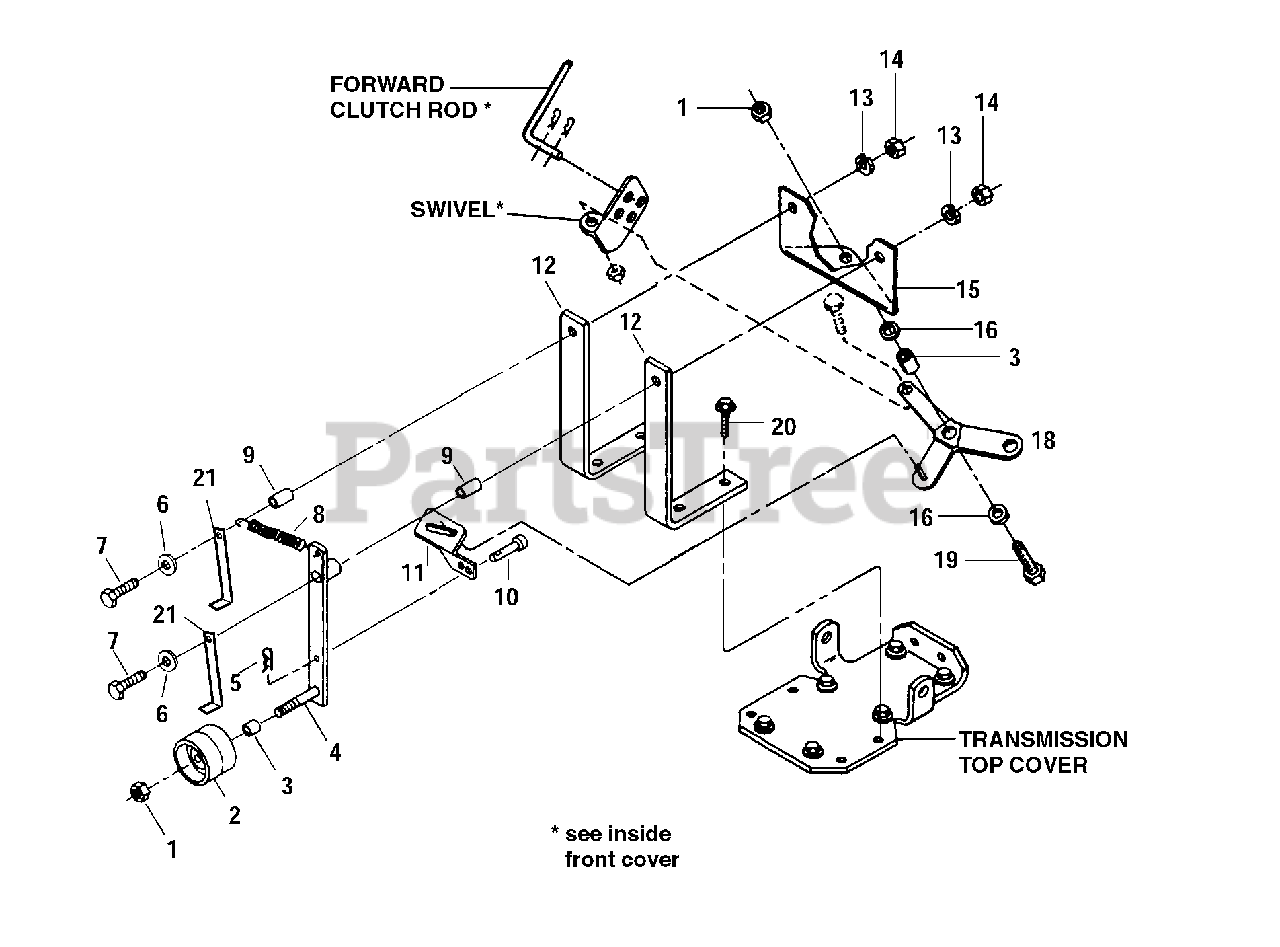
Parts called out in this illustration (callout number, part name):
1	Locknut-hex, 3/8-16
2	Pulley-idler, forward tiller
3	Spacer
4	Idler Arm-left, forward tiller direction
5	Hairpin Cotter
6	Washer-plain, 5/16
7	Screw-hex hd., 5/16-18 x 2-1/4
8	Spring
9	Pivot Bushing
10	Pin
11	Forward Link
12	Mounting Bar
13	Lockwasher-5/16
14	Nut-hex, 5/16-18
15	Shifting Base
16	Spacer-Bushing
19	Screw-hex hd., 3/8-16 x 1-1/4
20	Screw-flanged hex hd., 5/16-18 x 1
21	Belt Guide-forward belt
